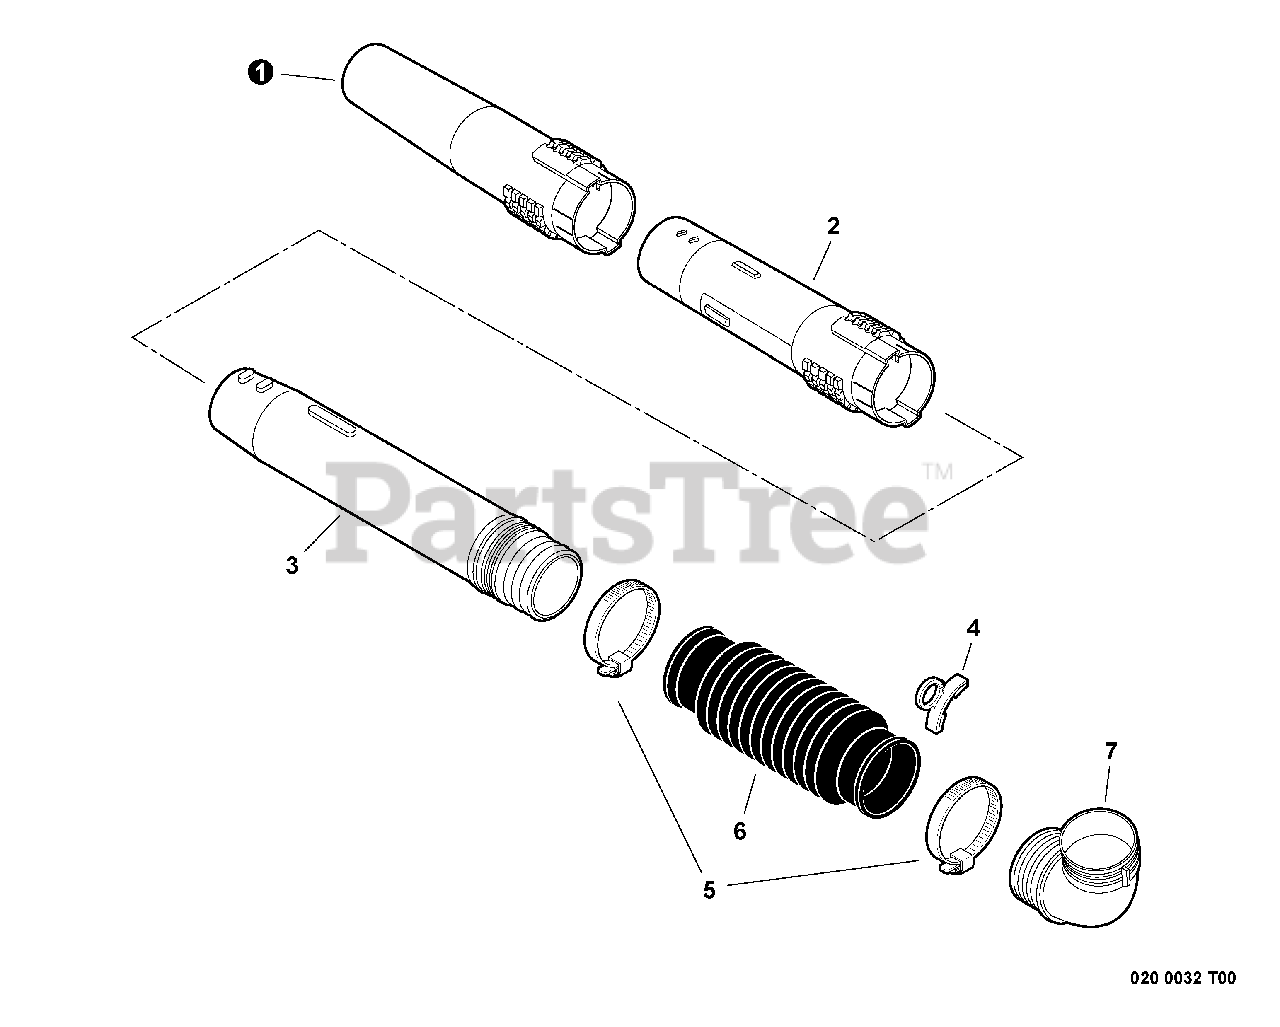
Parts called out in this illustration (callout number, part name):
1	TUBE, BLOWER - ROUND NOZZLE
2	TUBE, BLOWER - STRAIGHT
3	TUBE, BLOWER - SWIVEL
4	CLIP, CABLE
5	CLAMP 58.7 MM / 82.5 MM
6	TUBE, BLOWER - FLEXIBLE
7	TUBE, BLOWER - ELBOW
